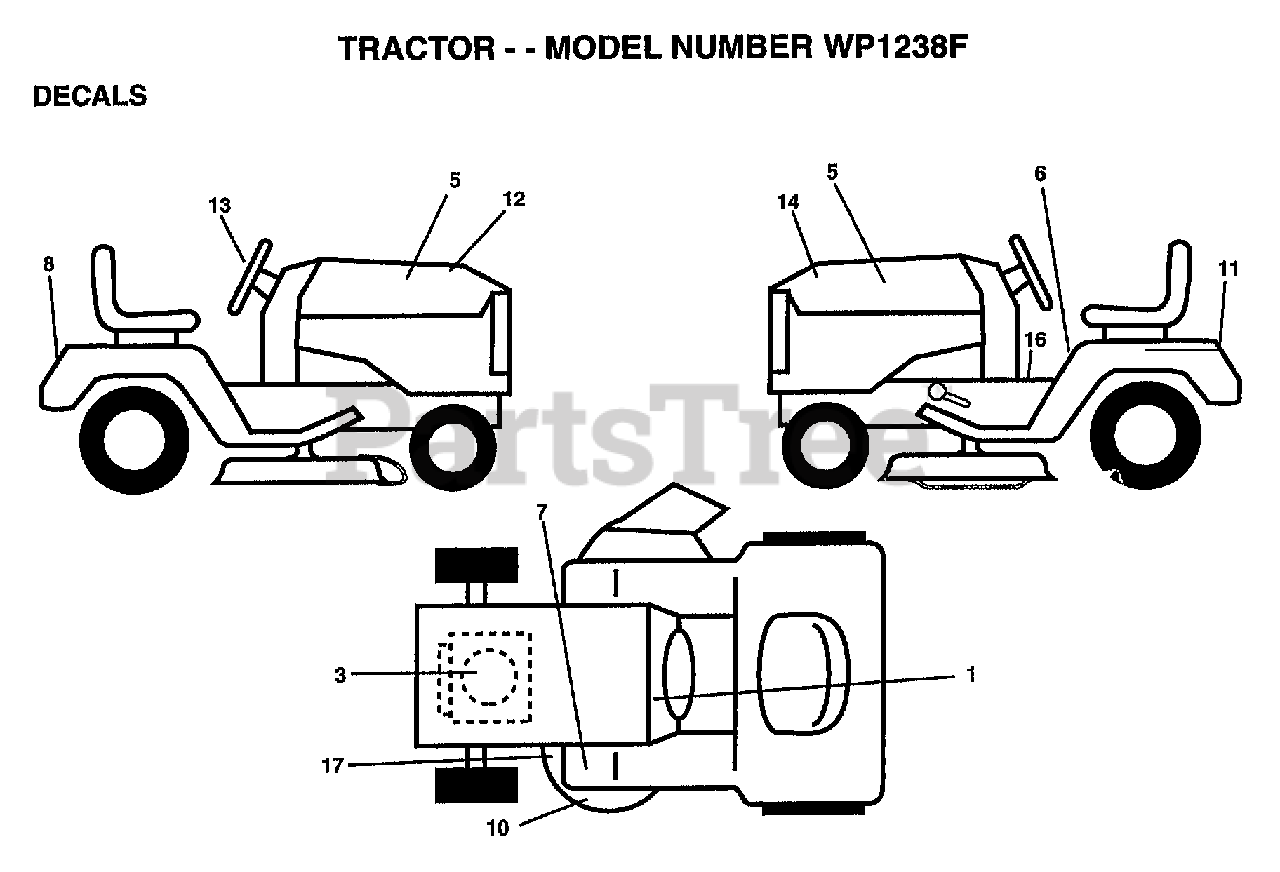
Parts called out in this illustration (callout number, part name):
1	"DECAL-OPER,GEAR D"
5	DECAL.HOOD.LOGO.
6	"DECAL DANGER,FEND"
8	DECAL, FENDER LOGO
11	DECAL.BATRY.3-3908
12	DECAL.HD.RH.WINST
13	DECAL, WHEEL CAP
14	DECAL.HD.LH.WINST
16	DECAL BRAK PARK
17	DECAL
